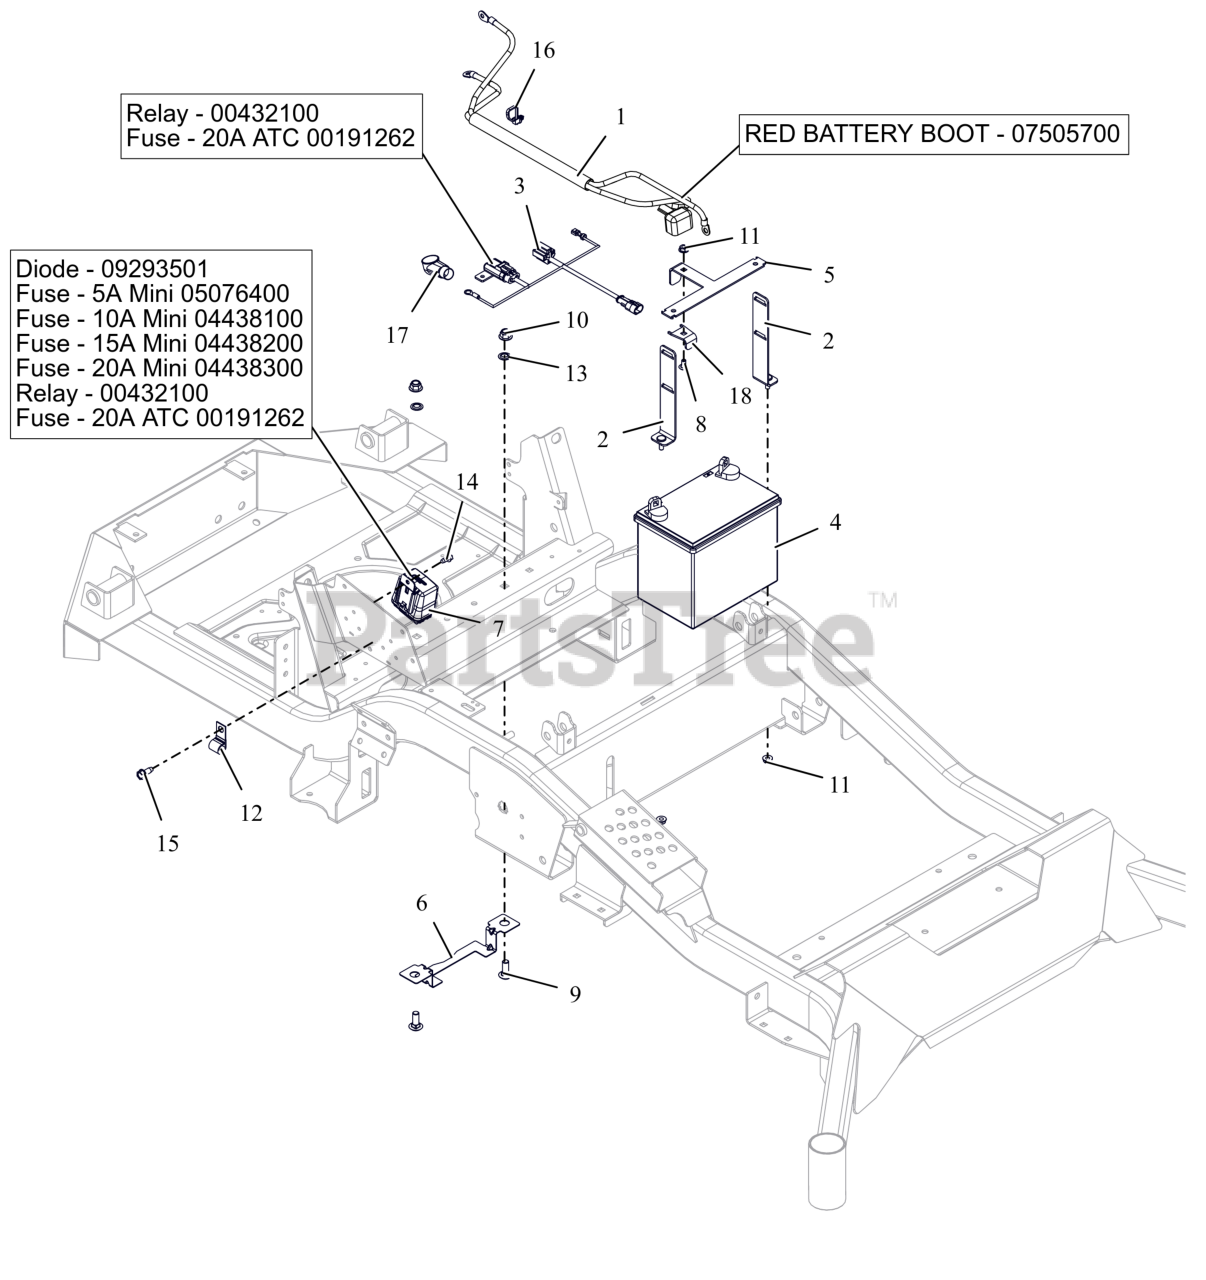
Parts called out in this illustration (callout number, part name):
1	HARNESS, BATTERY HD
1	INSULATOR
2	WMT,BATTERY MOUNT HOLD DOWN
3	HARNESS, STARTER ADAPTOR
3	RELAY,SEALED W/DIODE
3	FUSE, 20 AMP BLADE S/O
4	BATTERY, 300 CCA 10U1L
5	BRKT, BATTERY TIE DOWN
6	GUARD, ELECTRICAL HARNESS
7	HARNESS, WIRE
7	DIODE, CONNECTOR SHELL
7	FUSE, 5 AMP MINI-ATC
7	FUSE,10 AMP MINI-ATC
7	Fuse, 15 AMP MINI-ATC
7	FUSE,20 AMP MINI ATC
7	RELAY,SEALED W/DIODE
7	FUSE, 20 AMP BLADE S/O
8	BLT, RHSN .25-20X.500 G5 ZCC
9	BLT, RHSN .38-16X1.00 G5 ZCC
10	NUT,NYL-FLG .38-16 GF ZCC
11	NUT-LK-TOP-FLG .250-20 GF ZCC
12	J-CLAMP
13	NUT-PUSH .38 DIA. PAL ZINC
14	SCR-TAP .25-20X.50 HWH ZCC
15	SCR,TAP .312-18X.75 HWH TR ZCC
16	CABLE TIE W/ TREE (.25 HOLE)
17	BOOT, .65ID POS
18	BRKT, BATTERY HOLD
